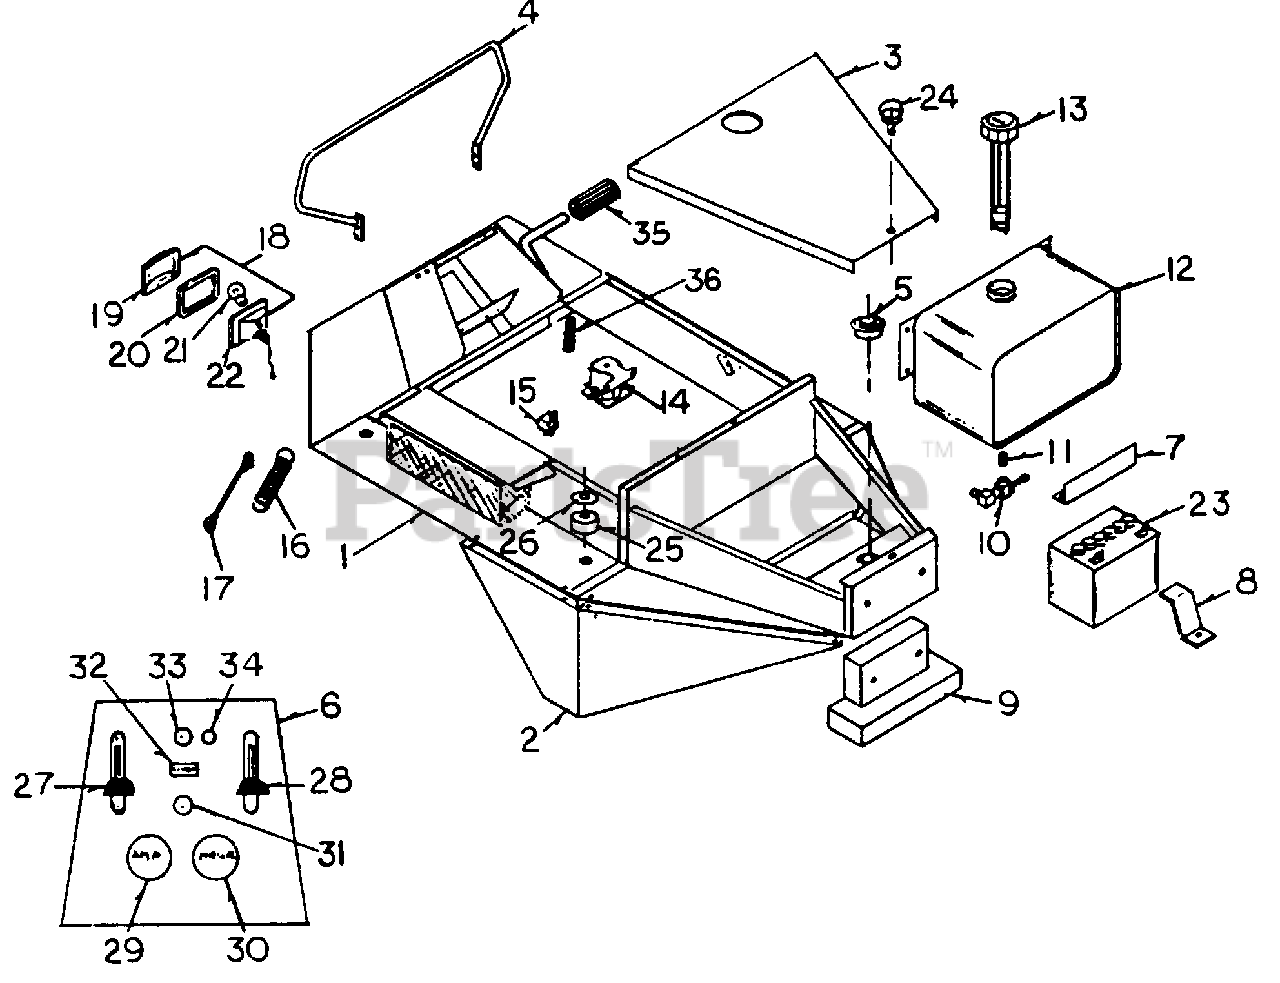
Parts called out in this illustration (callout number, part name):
1	Body
2	Fender, LH
7	Hold Down, Battery
8	Battery Post Protector
9	Tall Weight
10	Shutoff Valve, Fuel
11	Nlpple, 1/8" x Close
13	Fuel Tank Cap w/Gauge
15	Relay
17	Deck Llft Cable
19	Lens
20	Gasket
21	Bulb
23	Battery
25	Rubber Body Mount
26	Body Mount Washer
28	Throttle Cable
31	Ignition Swltch
32	Light Swltch
33	Clutch Swltch
35	Brake Pedal Pad
